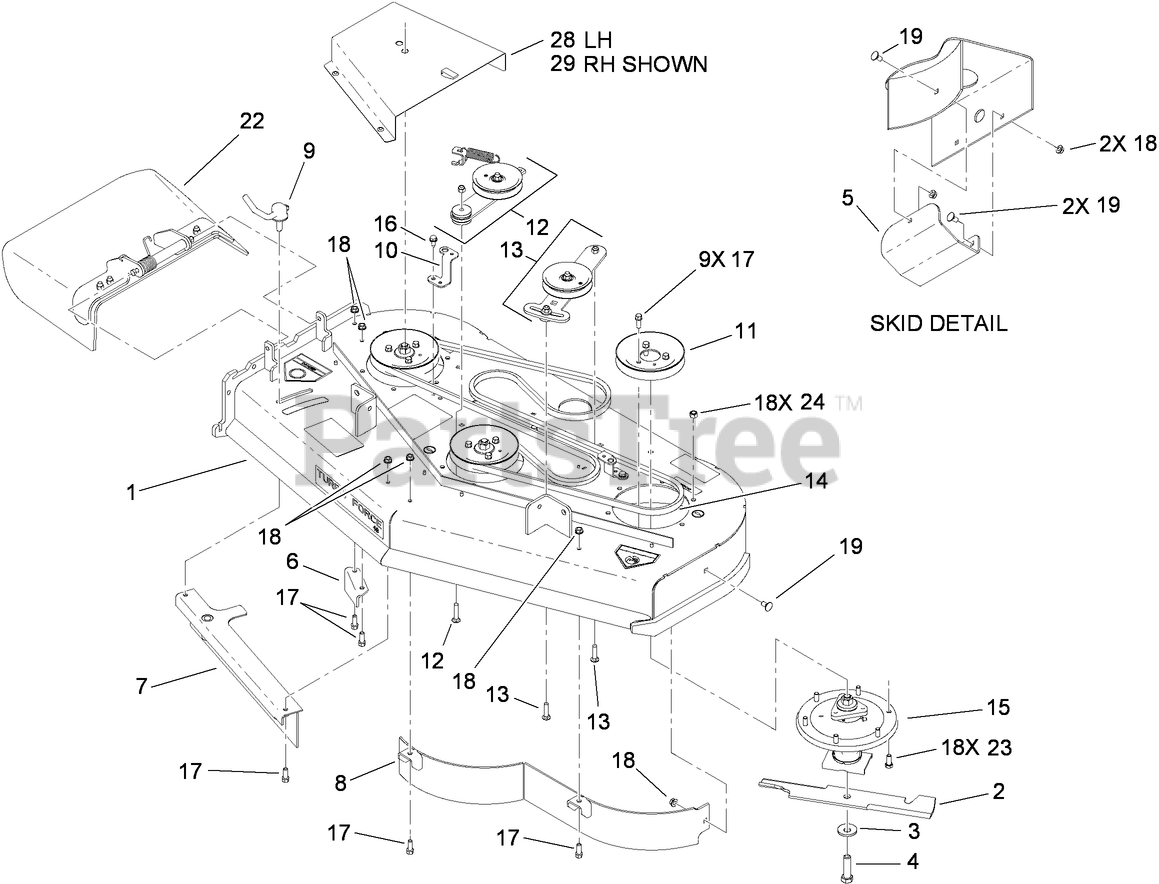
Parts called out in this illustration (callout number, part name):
1	DECK ASM
2	BLADE-16.5 INCH (HIGH FLOW)
3	Washer-Blade Bolt, Heavy
4	Screw-Cap
6	BAFFLE-DISCHARGE
8	48 INCH BAFFLE ASM
9	LEVER ASM
10	BRACKET-COVER, TALL
11	PULLEY
12	SPRING IDLER ASM
13	IDLER ADJUST ASM
14	BELT-V
15	SPINDLE ASM
16	SCREW-HWHTF
17	SCREW-HWH
18	NUT-HHF, WHIZ
19	SCREW-CARR
22	DEFLECTOR ASM
23	SCREW-HH
24	NUT-LOCK, NI
28	LH BELT COVER ASM
29	RH BELT COVER ASM
